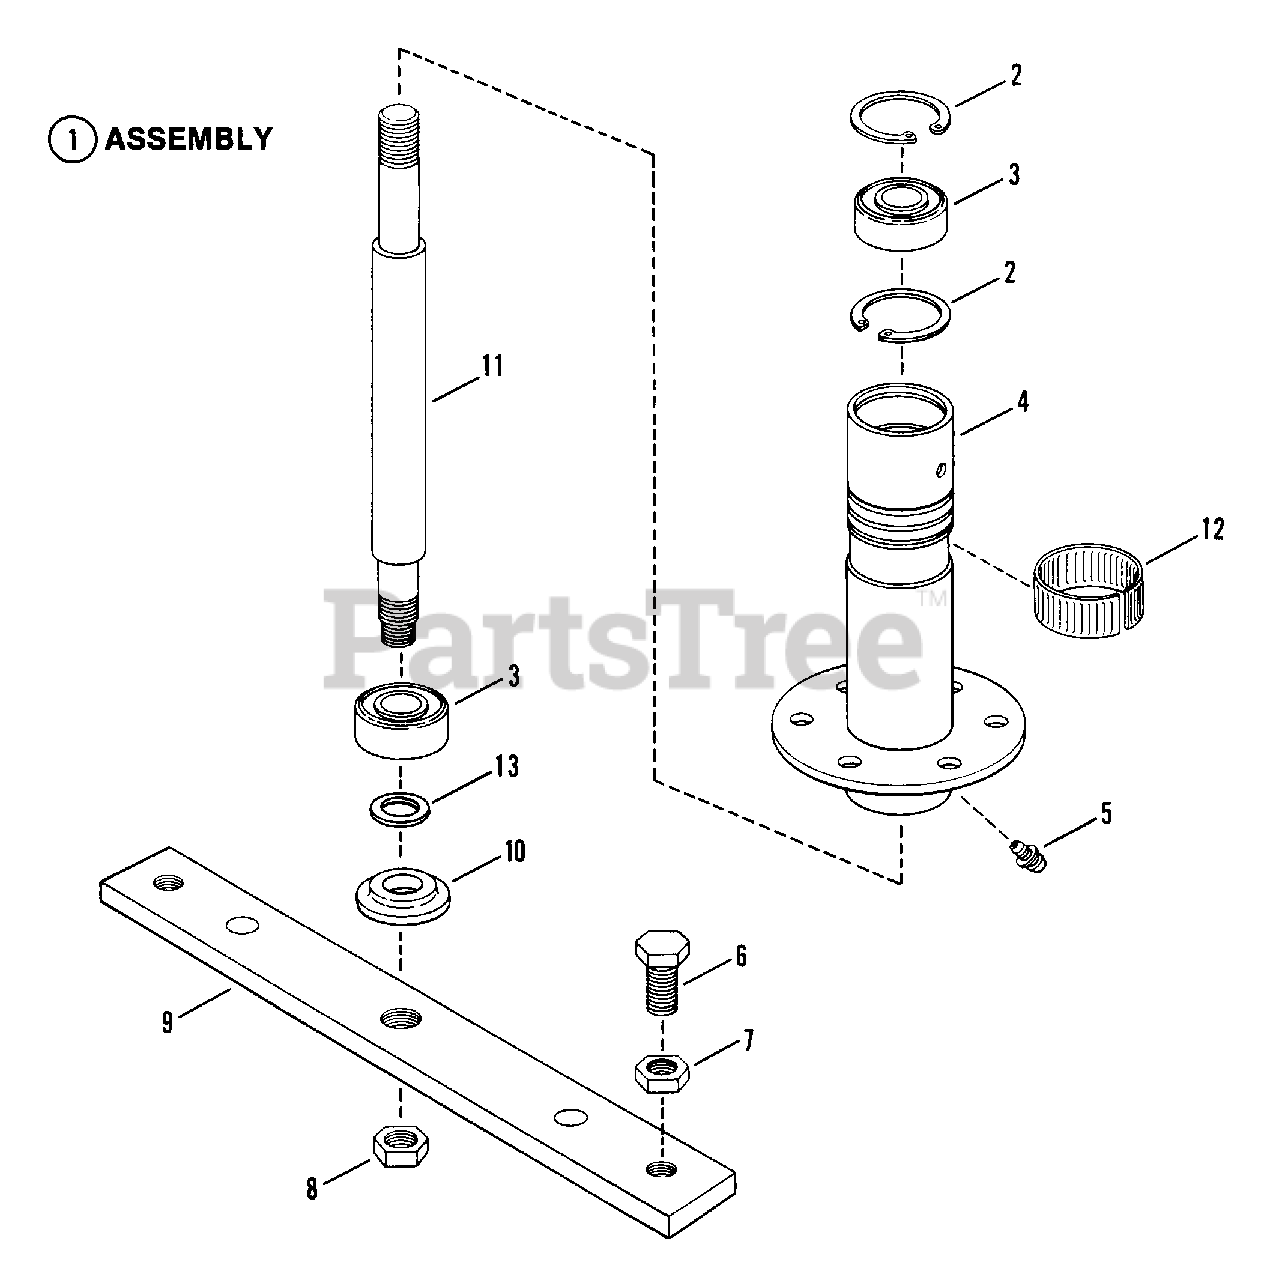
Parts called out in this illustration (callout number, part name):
1	ASSEMBLY, Spindle Housing
2	RING, Retaining
3	BEARING, Spindle
4	HOUSING, Spindle
5	FITTING, Lube (Press fit for .187 hole-no ball)
6	SCREW, 1/2-20 x 1" Hex Head Cap (GR.5)
7	NUT, 1/2-20 Hex Jam
8	NUT, 5/8-18 Hex Lock
9	HOLDER, Blade
10	WASHER, Spindle
11	SPINDLE, Shaft (10.237" Long)
12	RING, Tolerance
13	WASHER, Shim
